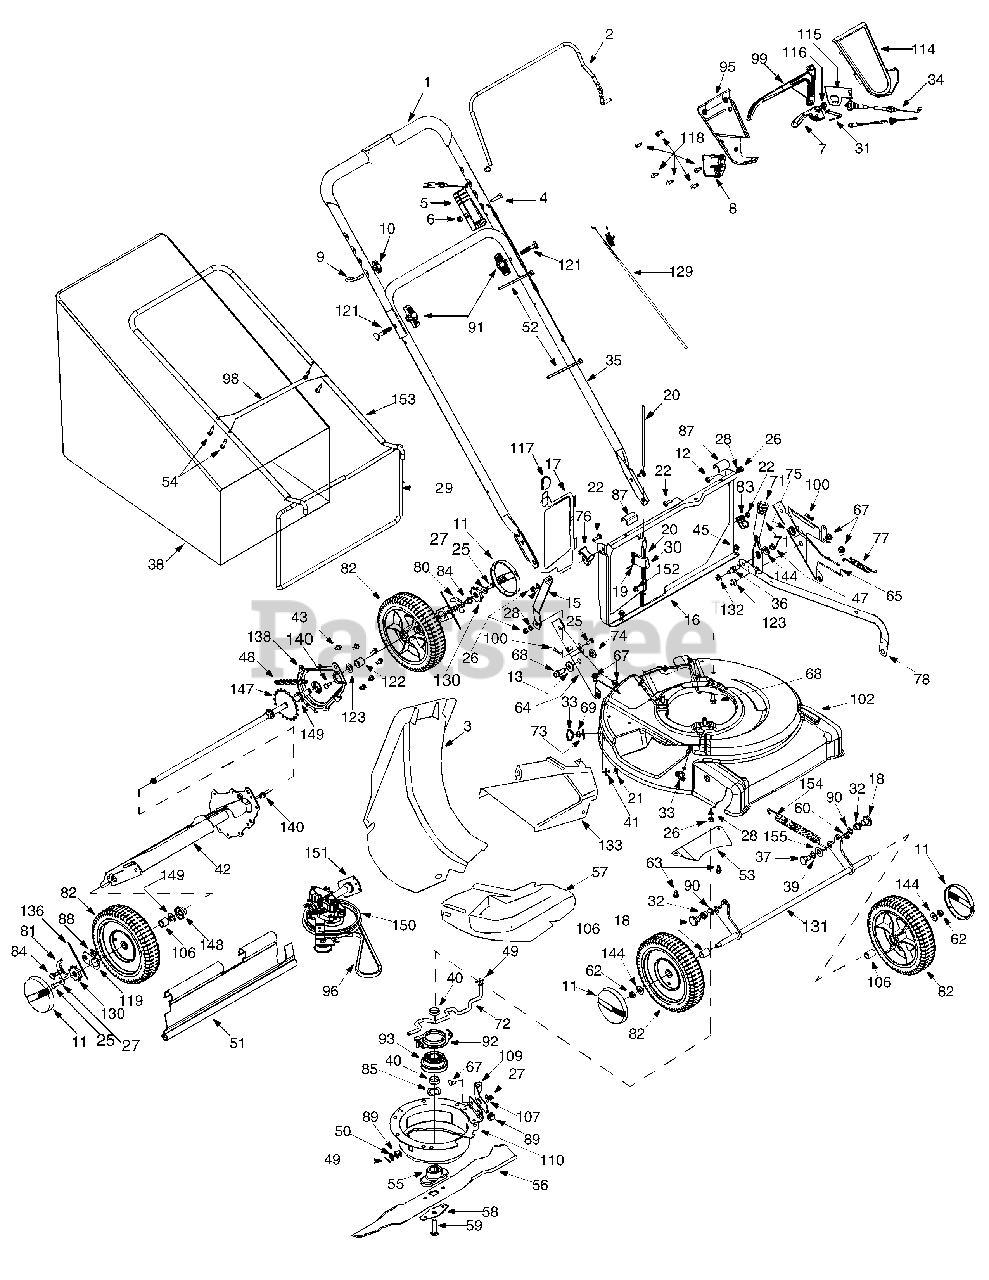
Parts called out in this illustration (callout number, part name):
1	Foam Handle
3	Rear Discharge Chute Assembly
4	Oval C-Sunk Screw
5	Control Housing
6	Hex Lock Nut
7	Shift Lever:3 Speed
8	Mounting Cover: Speed Cable
9	Rope Guide
10	Wing Nut
11	Hub Cap: Euro Gray
12	Truss Machine Screw
13	Flat Washer
19	Torsion Spring
20	Pivot Pin
21	Carriage Bolt
22	Truss Machine Screw
23	Clamp
24	Shoulder Bolt
25	Hex Bolt, 1/4-20 x 0.62''
26	Hex Nut, 1/4-20
27	Bell Washer, 1/4''
28	Lock Washer, 1/4''
30	Foam Strip
31	Shift Lever Spring
32	Flanged Bearing
33	Wing Nut w/Washer
34	Speed Cable
36	Shoulder Pin
37	Shoulder Screw
38	Grass Bag
39	Flat Washer
40	Spacer
41	Flat Washer
44	Wave Washer
45	Hex Tap Screw, 1/4'' x 0.62
46	Shoulder Screw
47	Hex Lock Nut, 3/8-24
48	#48 Chain .500'' Pitch x 30 Links
49	Cotter Pin
50	Flat Washer
51	Rear Flap
52	Cable Tie
55	Blade Adapter Kit
56	21'' Mulching Blade
57	Mulch Plug
58	Blade Bell Support
59	Hex Bolt, 3/8-24 x 1.5''
60	Jam Nut
61	Spacer
62	Lock Nut
63	Hex B-TT Scrwe
67	Hex tap Screw, 5/16-18
68	Hex Tap Screw, 3/8-16
69	Hex Nut, 5/16-18
71	Height Adjustment Lever
72	Shift Rod
73	Bell Washer
74	Spacer
75	Shoulder Spacer
76	Rope Guide
77	Extension Spring
78	Lever Connection Arm
79	Bearing, 1/2'' OD
80	Pawl - LH
81	Pawl - RH
82	Wheel Assembly
83	Clamp
84	Shoulder Screw
85	Spring Washer
86	Crankshaft Spacer
87	Panel Clip
88	Weld Lock Nut
89	Flanged Bushing
90	Wave Washer
91	Hand Knob
92	Upper Pulley Half: Variable Speed
93	Lower Pulley Half: Variable Speed
94	Machine Screw, 1/4-20
95	Upper Housing
96	V-Belt
97	Sems Nut, 1/4-20
98	Bag Handle
99	Drive Clutch Control Lever
100	hairpin Clip
107	Lock Nut
108	Compression Spring
115	Cable Bracket
116	Gear: Rack
117	Door Grip
118	C-Sunk TT Screw
119	Compression Spring
121	Curved Carriage Bolt
122	Shoulder Pin
123	Lock Washer
129	Control Cable: 44''
130	Ratcher Wheel
131	Front Axle
132	Hex Jam Nut
133	Side Discharge Chute
134	Hex Flange Bearing
136	Plastic Spacer: Ratchet
144	Flat Washer
147	Rear Shaft Assembly
148	Hex Flange Bearing
149	Flat Washer
150	Transmission Assembly Complete
152	Hex TT Screw #10 x 0.38''
154	Extention Spring
155	Belleville Washer
